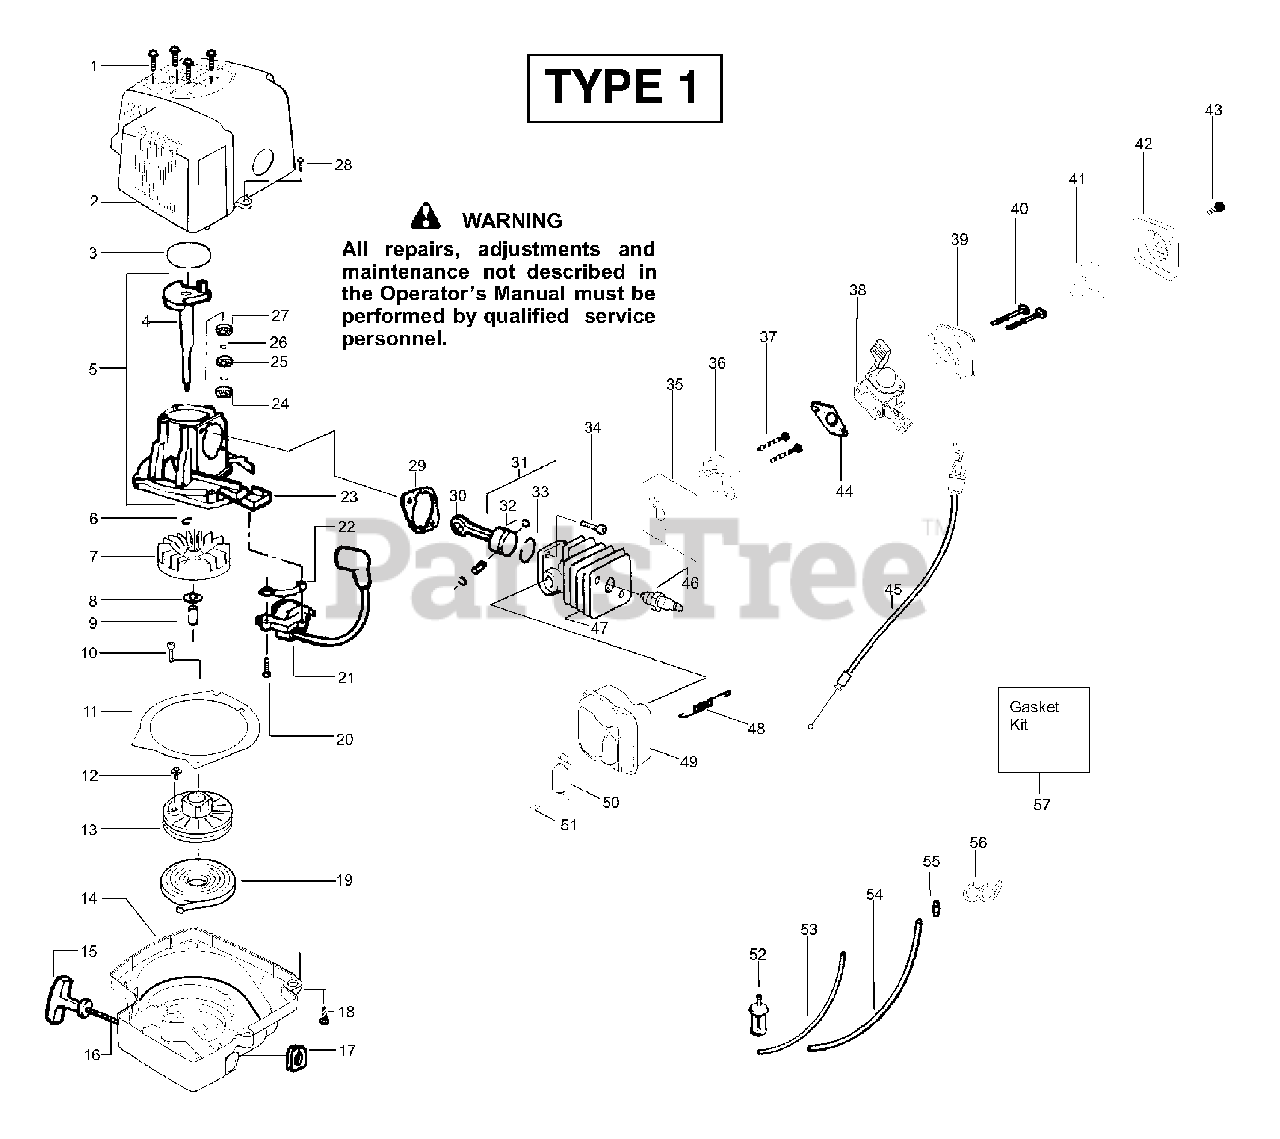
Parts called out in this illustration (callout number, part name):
2	Assy-Shroud/H'shield
3	O-Ring-Shrd/C'case
4	Assy-Crankshaft
5	Assy-C/case-C/shaft
6	Ring-Retainer-C'shaft
7	Assy-Flywheel
8	Washer-Flat
9	Spacer-Flywheel
11	Plate-Baffle
13	Kit-Starter Pulley
14	Assy-Fan Housing
15	Handle-Starter
16	Kit-Rope
17	Grommet-Ignition Module
18	Screw-(f/hsg to shrd)
19	Spring-Starter
21	Ignition Module
22	Spacer-Ign. Module
23	Assy-Crankcase
24	Bearing-Outer
25	Seal-Crankcase
26	Ring-Retainer-C'case
27	Bearing-Inner
29	Gasket-Cylinder
30	Assy-Connecting Rod
31	Kit-Piston
32	Retainer-Piston Pin
33	Ring-Piston
35	Gasket-Cyl./Carb. Adapt.
36	Adapter-Carburetor
38	Kit-Carburetor Ass'y. (C1U-W13)
38	Kit-Carburetor Ass'y. (C1U-W13A)
41	Air Filter Foam
42	Air Filter Cover
44	Gasket-Carburetor
45	Assy-Throttle Cable
46	Spark Plug(RCJ-7Y)
47	Kit-Cylinder
48	Spring-Muffler
49	Kit-Muffler
50	Kit-Spark Arrestor
52	Assy-Pick-up
53	Kit-Fuel Line (small)
54	Kit-Fuel Line (large)
55	Fitting-Fuel Line
56	Clip-Retainer
57	Kit-Gasket
